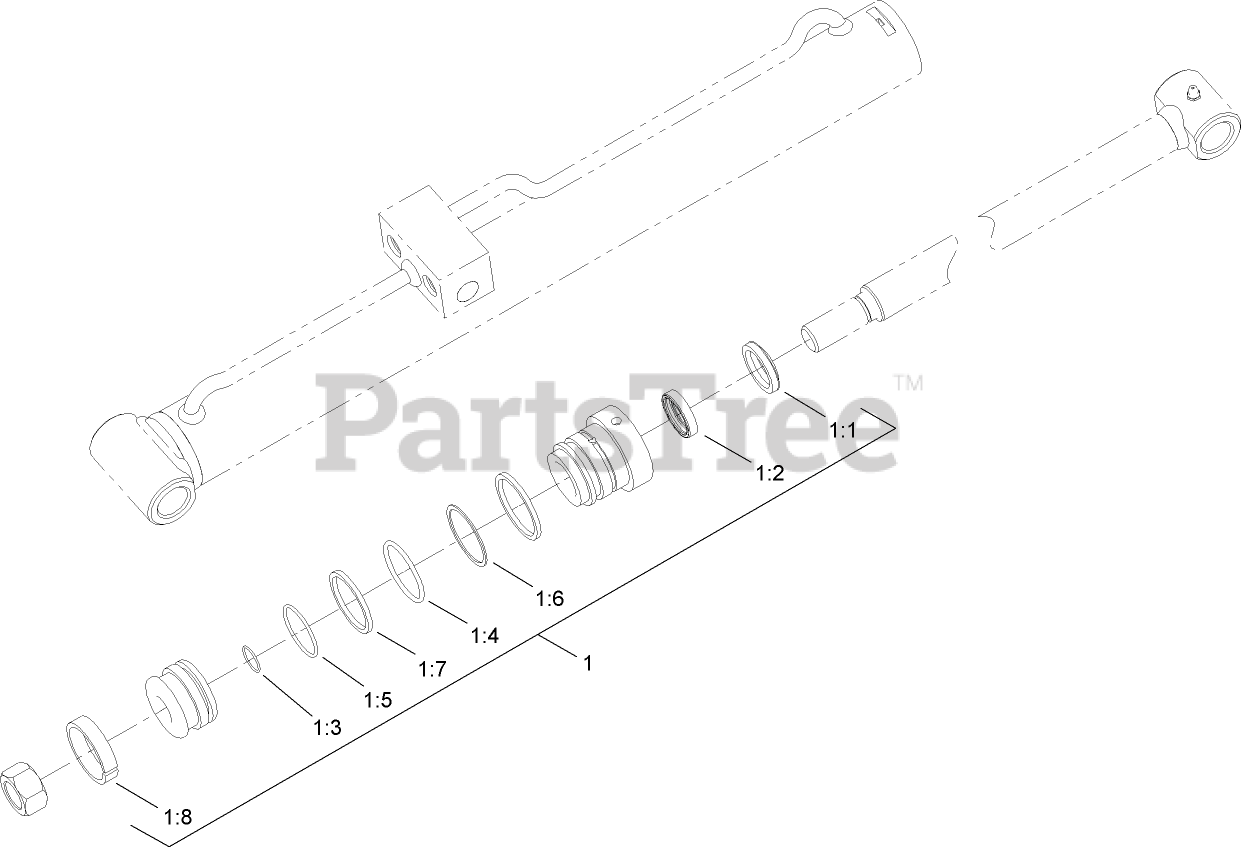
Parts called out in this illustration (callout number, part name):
1	SEAL KIT
1:1	WIPER
1:2	SEAL
1:3	O-RING
1:4	O-RING
1:5	O-RING
1:6	Back-Up
1:7	SEAL
1:8	WEAR RING
